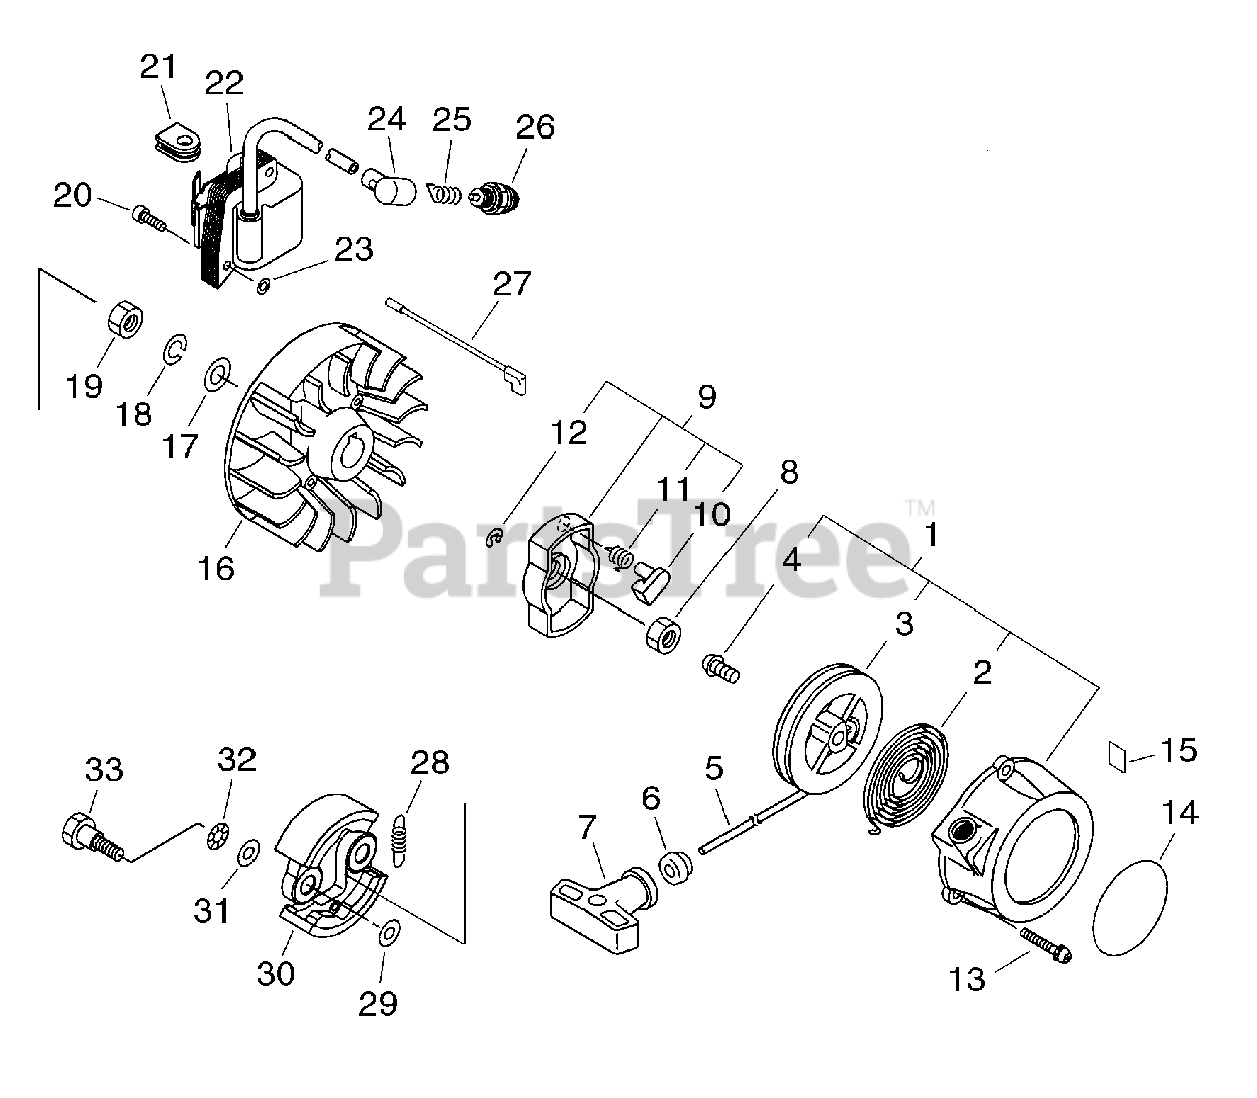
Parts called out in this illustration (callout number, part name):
1	STARTER ASSY, RECOIL
2	SPRING, RECOIL
3	REEL, ROPE
4	SCREW
5	ROPE, STARTER 3×800
6	GUIDE, ROPE
7	GRIP, STARTER
8	NUT 8×1.25
9	PAWL ASSY, STARTER
10	PAWL, STARTER
11	SPRING, RETURN
12	E-RING 4
13	SCREW 4×14
14	LABEL, RECOIL STARTER
15	LABEL, CAUTION - HOT
16	FLYWHEEL
17	WASHER 8.5×16×1.2
18	WASHER, SPRING 8
19	NUT 8×1.25
20	BOLT 4×22
22	COIL, IGNITION
24	CAP, SPARK PLUG
25	TERMINAL, SPARK PLUG
26	SPARK PLUG - BPM7Y
28	SPRING, TENSION
29	WASHER 6
30	SHOE, CLUTCH
31	WASHER 8
32	WASHER, SPRING 8.5×16×0.5
33	BOLT, CLUTCH 8×7.9×M6
